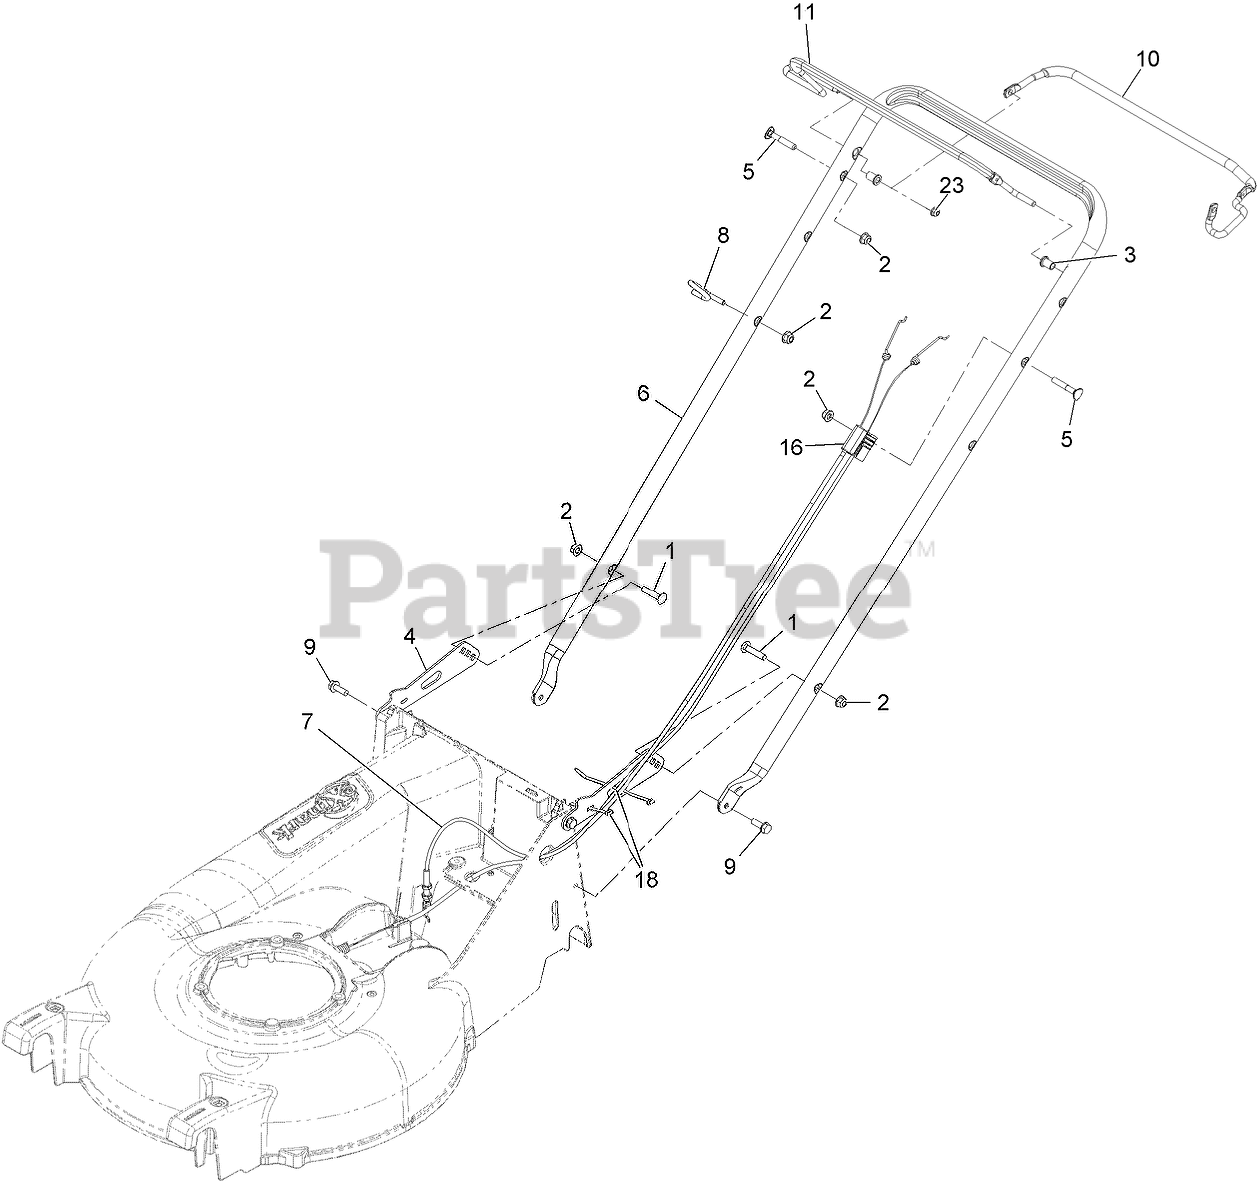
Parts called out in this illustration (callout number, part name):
1	BOLT-CARR
2	NUT-HF, NI
3	BUSHING-HANDLEBAR
4	BRACKET,HANDLEBAR
6	HANDLEBAR-P21
7	CABLE, DRIVE EC21
8	GUIDE,ROPE
9	SCREW-TAPTITE
11	BAIL,OPC/BBC
16	CABLE-ZONE KAWASAKI
18	TIE-CABLE
